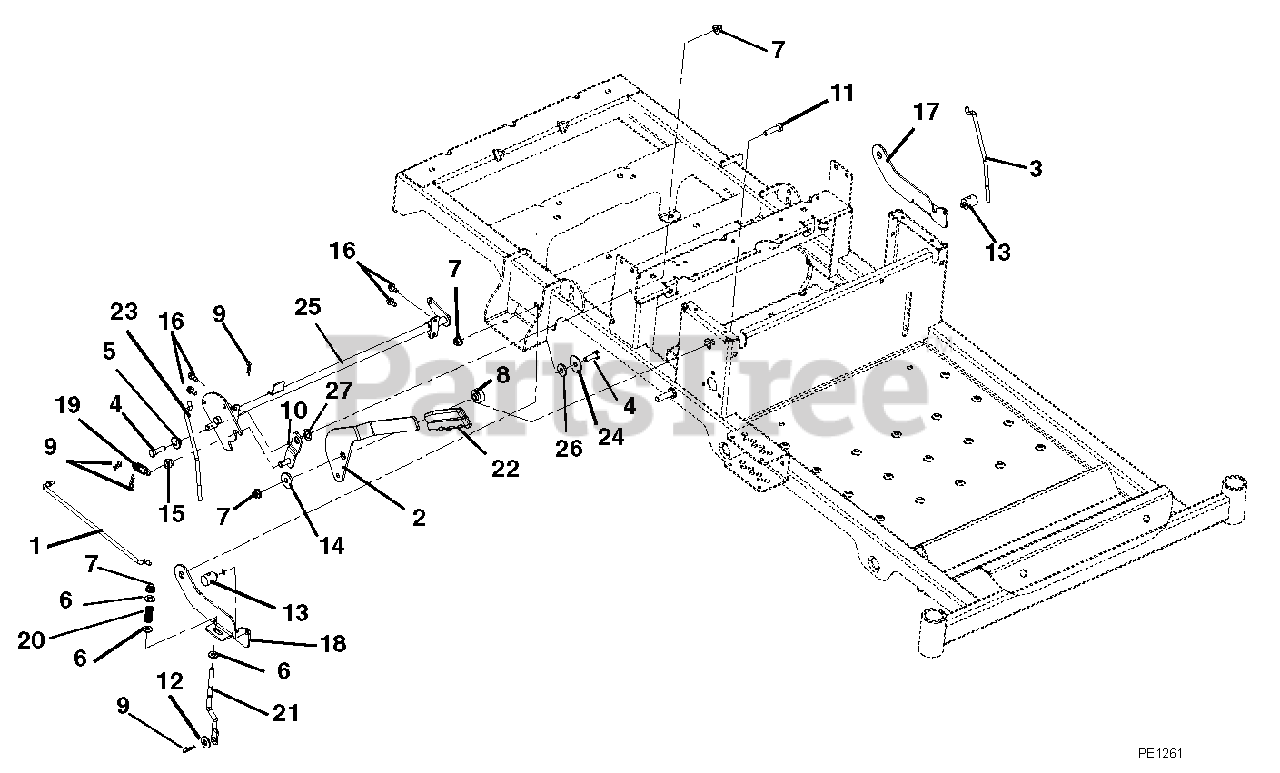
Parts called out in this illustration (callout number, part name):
1	Link, Brake Handle
2	Handle, Parking Brake
3	Link, Neutral LH
4	Bolt, Hex .31-18 x 1.00 Grade 5
5	Bushing, Flange .312 x .500 x .344 x .880
6	Washer, Flat-Steel .344 x .688 x .065
7	Nut, Flange Nyloc 5/16-18
8	Spacer, Brake Handle
9	Pin, Hair Internal .08 x .18 x 1.18
10	Weldment, Detent Arm
11	Bolt, Hex .31-18 x 1.25 Grade 5
12	Washer, Flat Steel .38 x .875 x .083
13	Trunnion, 1/4-20
14	Washer, Flat Steel .344 x 1.125 x .135
16	Screw, Tapping .25-20 x .50 Hex Washer Head
17	Latch, LH Neutral
18	Latch, RH Neutral
19	Spring, Tension .072 x .565 x 1.87
20	Spring, Compression
21	Link, Brake Cog
22	Grip, Park Brake
23	Link, Neutral RH
24	Washer, Flat Steel .347 x 1.254 x .048
25	Weldment, Brake Shaft
26	Bushing, Flange .325 x .499 x .26 x .88
27	Washer, Flat-Steel .754 x 1.125 x .062
